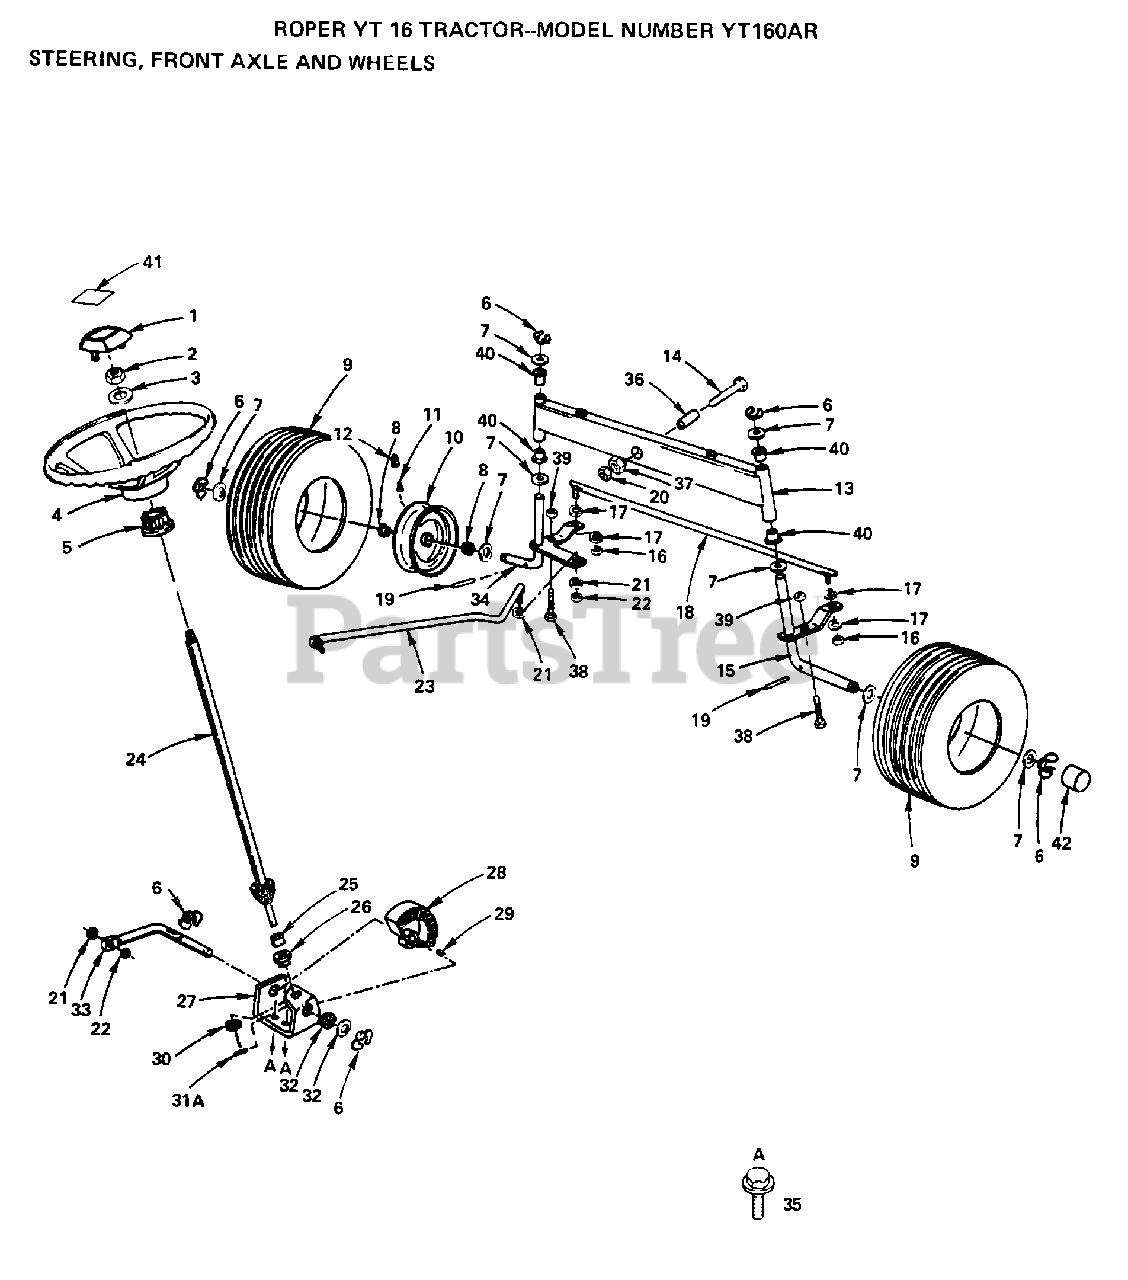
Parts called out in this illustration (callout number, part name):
1	INSERT-WHEEL LT
2	NUT
3	WASHER
5	ADAPTER LT
6	RING
8	"FLANGE, BEARING"
11	VALVE STEM LT
12	VALVE CAP
13	AXLE ASSY YTV
16	NUT
17	LOCKWASHER
20	LOCKNUT M
21	LOCKWASHER
23	DRAG LINK LTV
25	SHAFT SPACER LT
26	BUSHING
28	GEAR-SECTOR T
30	WASHER D
32	WASHER .T
33	ROD STEERING LT
34	SPINDLE LH LTV
35	SCREW
38	BOLT
39	NUT
40	COL. SRTG. BEAR.
41	DECAL - STEERING WHEEL
42	HUB CAP
